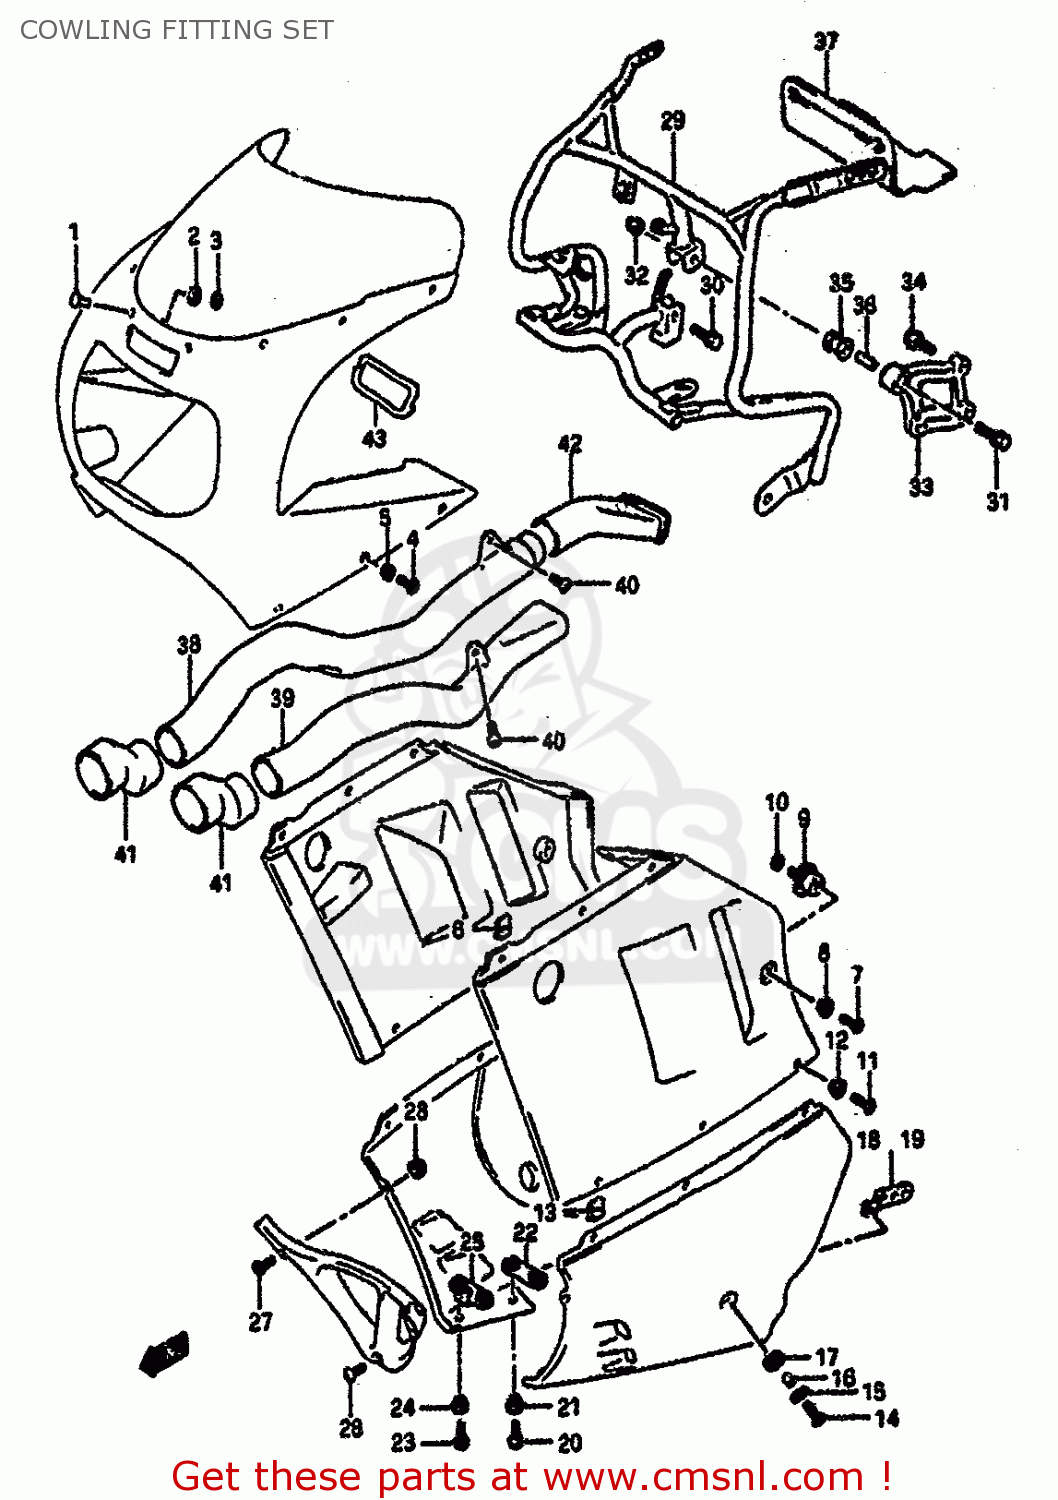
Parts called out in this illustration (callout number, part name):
1	PIN,WINDSCREEN
2	CUSHION
3	NUT
4	SCREW(5X18)
5	WASHER(5.2X14X1.5)
6	NUT,HEADLAMP HOUSING,UPPER
7	SCREW(6X12)
8	WASHER(6.3X16X1.5)
9	CUSHION,COWLING
10	WASHER,LOCK
11	SCREW(5X18)
12	WASHER(5.2X14X1.5)
13	NUT,HEADLAMP HOUSING,UPPER
14	SCREW(6X20)
15	WASHER(6.5X18X1)
16	SPACER
17	CUSHION
18	BRACE,COWLING LWR,R
19	BRACE,COWLING LWR,L
20	SCREW(6X16)
21	WASHER(6.3X16X1.5)
22	BRACE,COWLING LWR COVER RR
23	SCREW(6X16)
24	WASHER(6.3X16X1.5)
25	BRACE,COWLING LWR COVER
26	SCREW(6X16)
27	SCREW(5X14)
28	NUT
29	BRACE,COWLING
30	BOLT, BRACE (8X30)
31	BOLT
32	NUT ,8MM
33	BRACE,COWLING CTR
34	BOLT, BRACE CENTER (8X40)
35	CUSHION,COWLING BRACE
36	SPACER
37	SHEET,COWLING HEAT GUARD
38	PIPE,AIR INTAKE FR,R
39	PIPE,AIR INTAKE FR,L
40	SCREW, CENTER
41	JOINT,AIR INTAKE
42	PIPE,AIR INTAKE RR,R
43	CUSHION,FR POSITION LAMP
